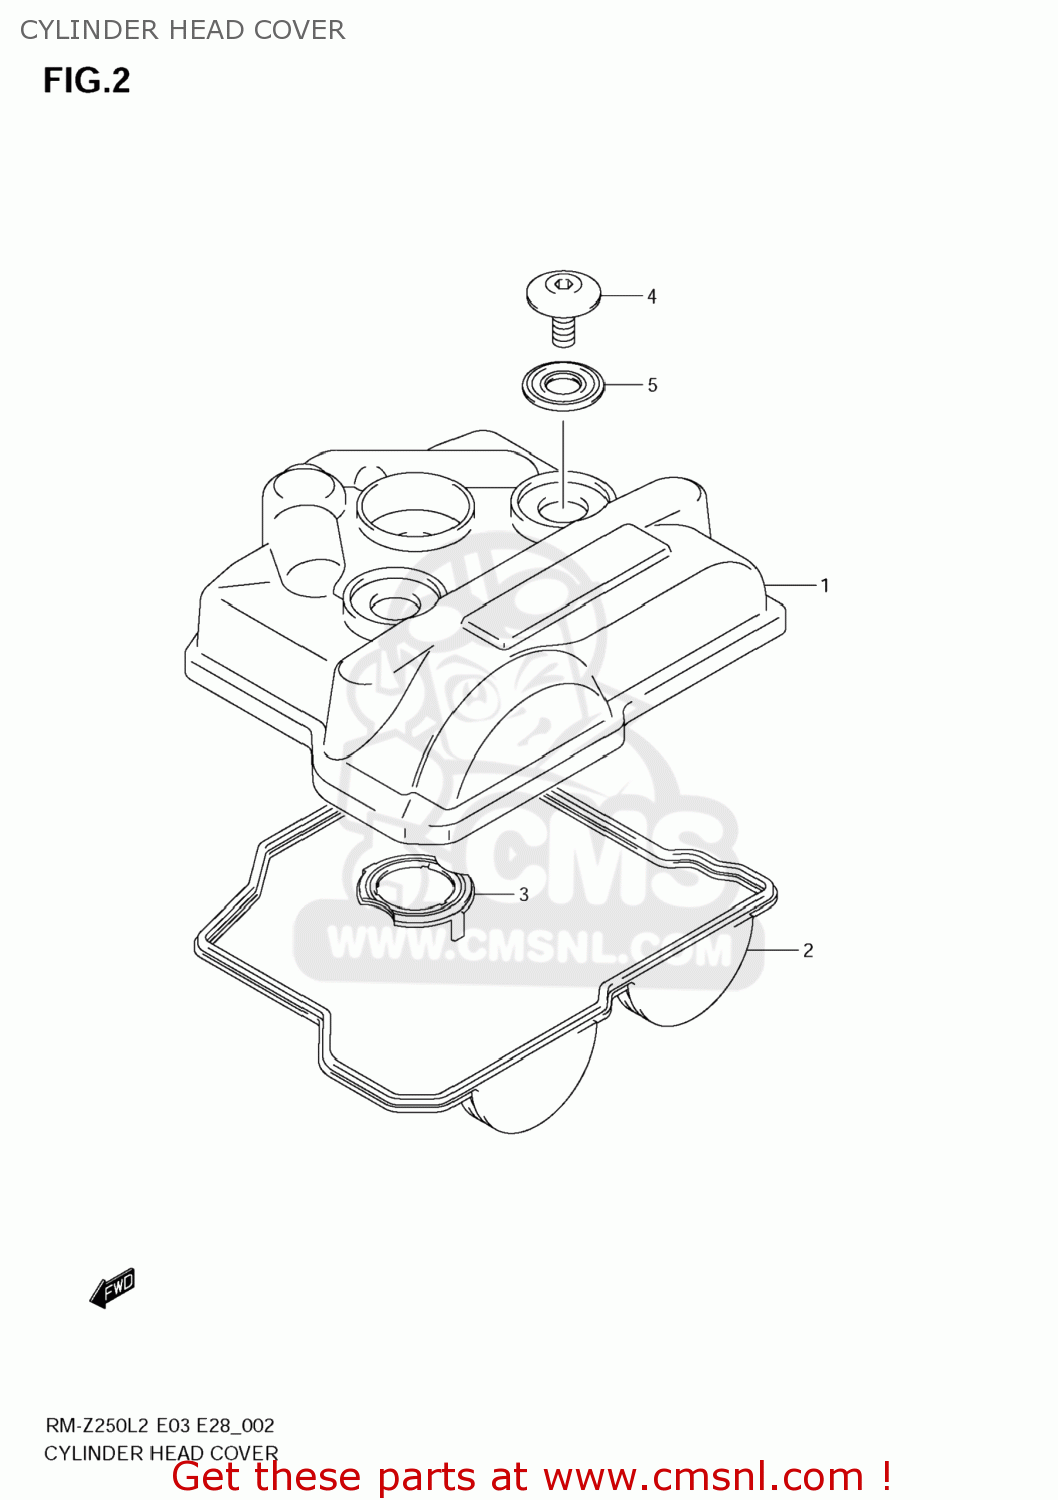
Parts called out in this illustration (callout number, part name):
1	COVER,CYLINDER HEAD
2	GASKET,CYL HEAD COVER NO.1 (NAS)
3	GASKET,CYL HEAD COVER NO.2 (NAS)
4	BOLT(7X17.5)
5	WASHER,CYL HEAD COVER
